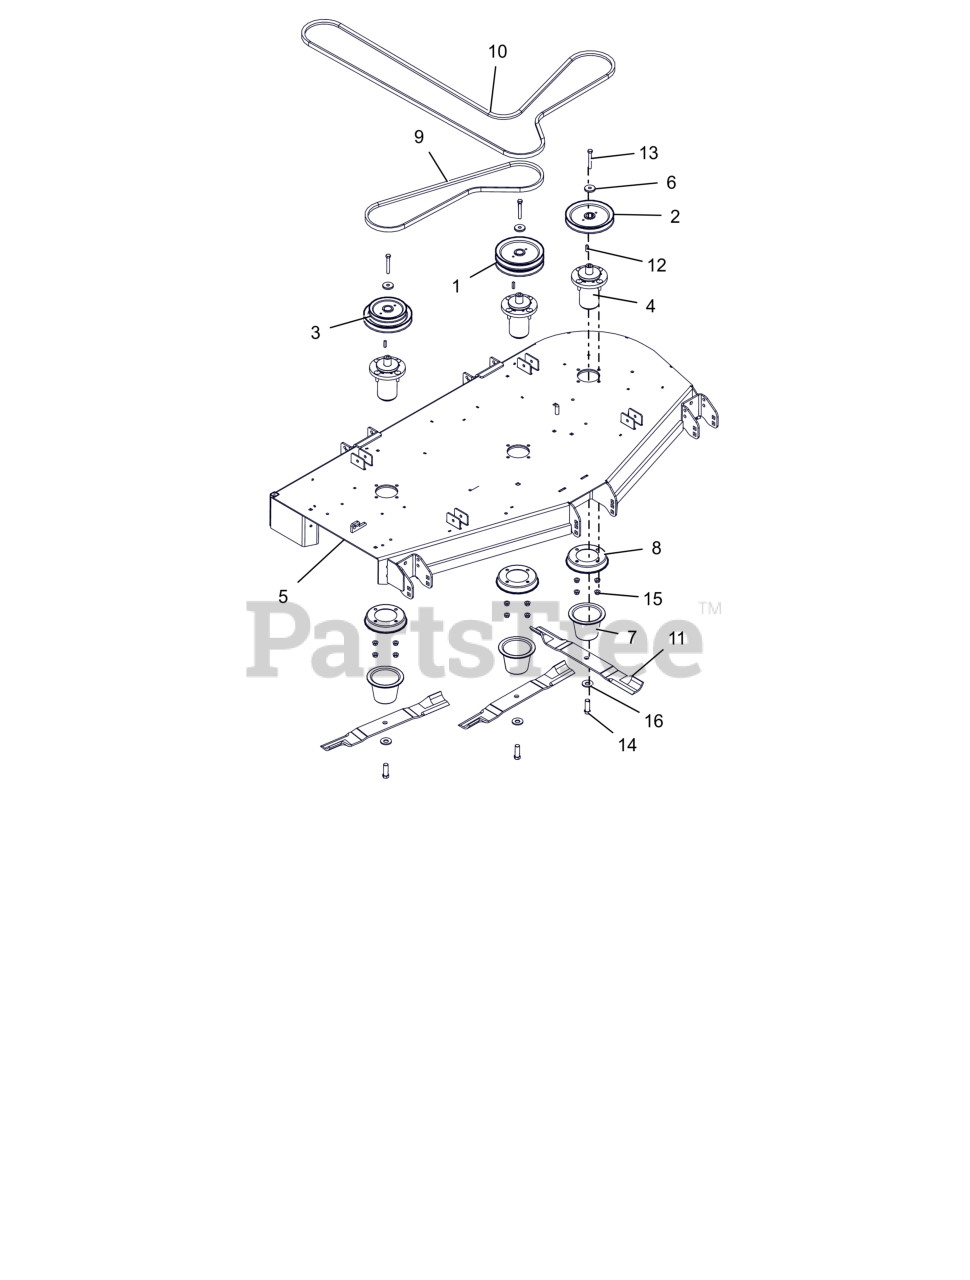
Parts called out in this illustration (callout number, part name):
1	PULLEY, DOUBLE-1"ID X 6.75"OD
2	PULLEY, V-1" ID X 6.75" OD
3	PULLEY, DBL-1"IDX6.75"&5.25"OD
4	ASM, MAINT FREE ALUM SPINDLE
5	WLDMT, 60" SIDE DISCH DECK (RED)
6	RETAINER, SHEAVE
7	GUARD, SPINDLE LOWER
8	GUARD, SPINDLE TOP
9	V-BELT, B-COGGED
10	V-BELT, HB-WRAPPED
11	BLADE, MOWER (20.50")
12	KEY, SQ .25X.25X1.00 RC 40-50
13	BLT, HEX .38-16X2.75 G8 ZCC
14	BLT, HEX .62-18X1.75 G8 ZCC
15	NUT-LK-CTR-FLG .375-16 GF ZCC
16	WSHR-BLVL .669X1.535X.138
